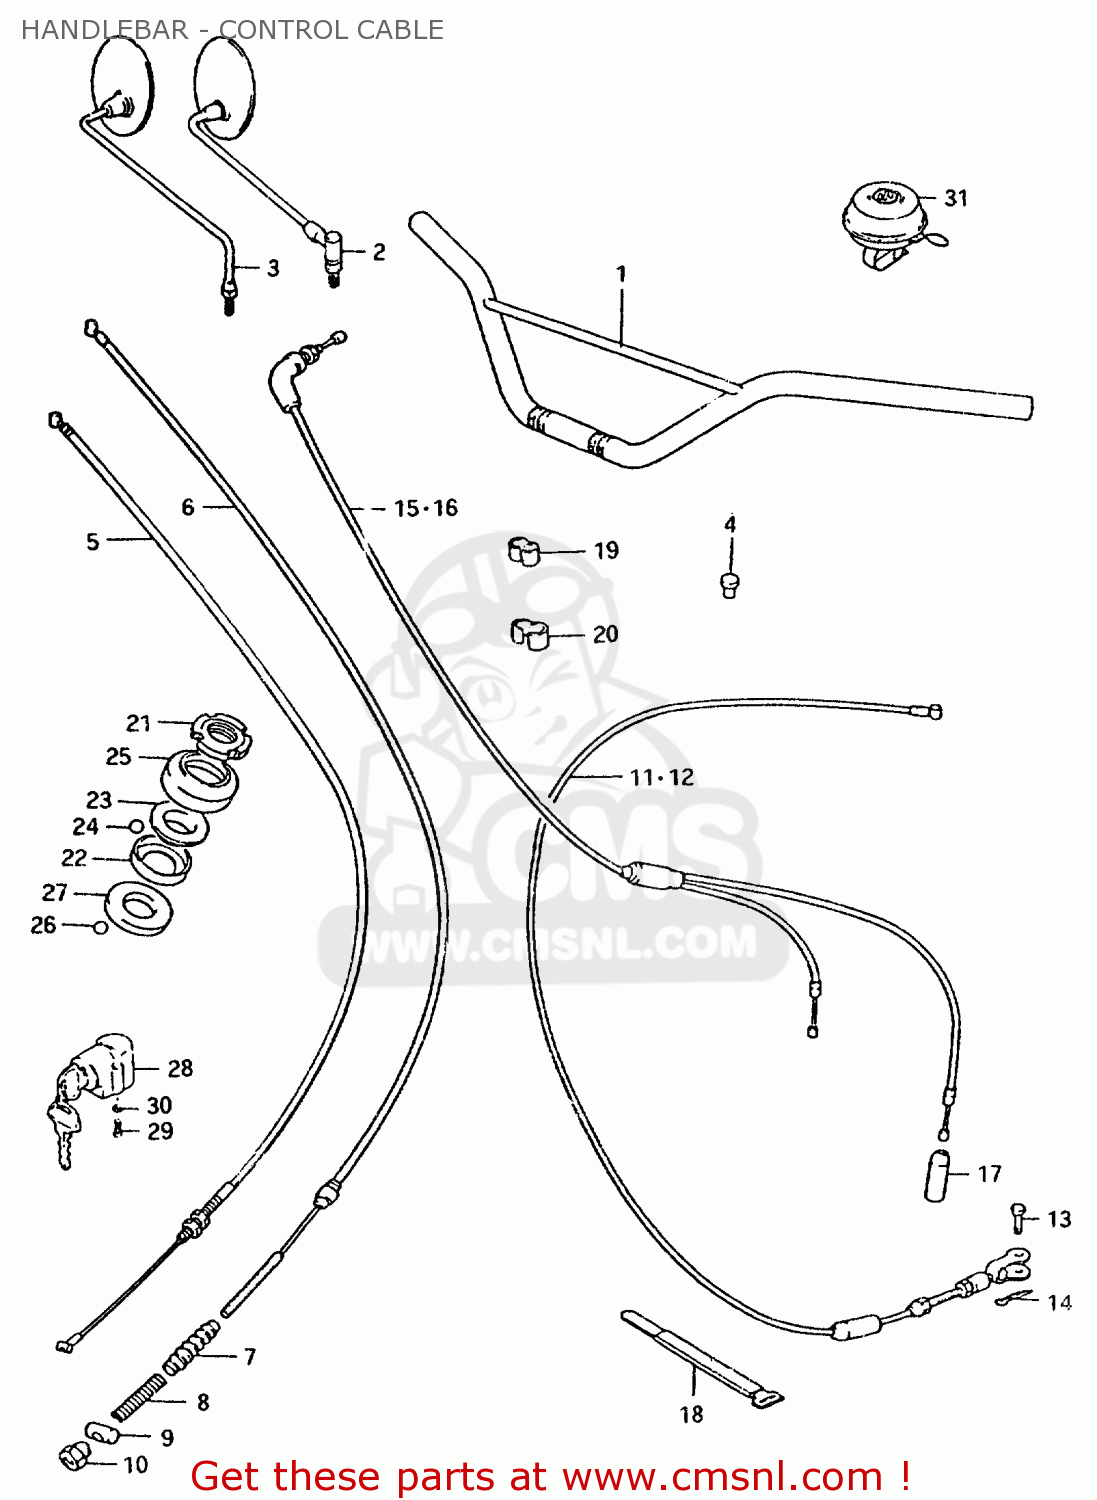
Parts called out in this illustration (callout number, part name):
1	HANDLEBAR
2	MIRROR ASSY, REAR VIEW RH
3	MIRROR, REAR VIEW LH
4	CAP
5	CABLE ASSY, BRAKE
6	CABLE ASSY, BRAKE
7	SEAL,DUST(7X16X75)
8	SPRING
9	PIN,10X19
10	NUT
11	CABLE ASSY,CLUTCH
12	CABLE ASSY,CLUTCH
13	PIN(L:13)
14	PIN
15	CABLE ASSY, THROTTLE
16	CABLE ASSY, THROTTLE
17	SEAL,DUST(7X18X30)
18	CLAMP
19	CLIP
20	CLIP
21	NUT,STEERING STEM(25X44X10)
22	RACE,STEERING INNER UPR
23	RACE,STEERING OUTER UPR
24	BALL
25	DUST SEAL,STEERING UPR
26	BALL
27	LACE,STEERING INNER LWR
28	LOCK ASSEMBLY,STEERING
29	SCREW
30	LOCK WASHER
31	BELL ASSY
